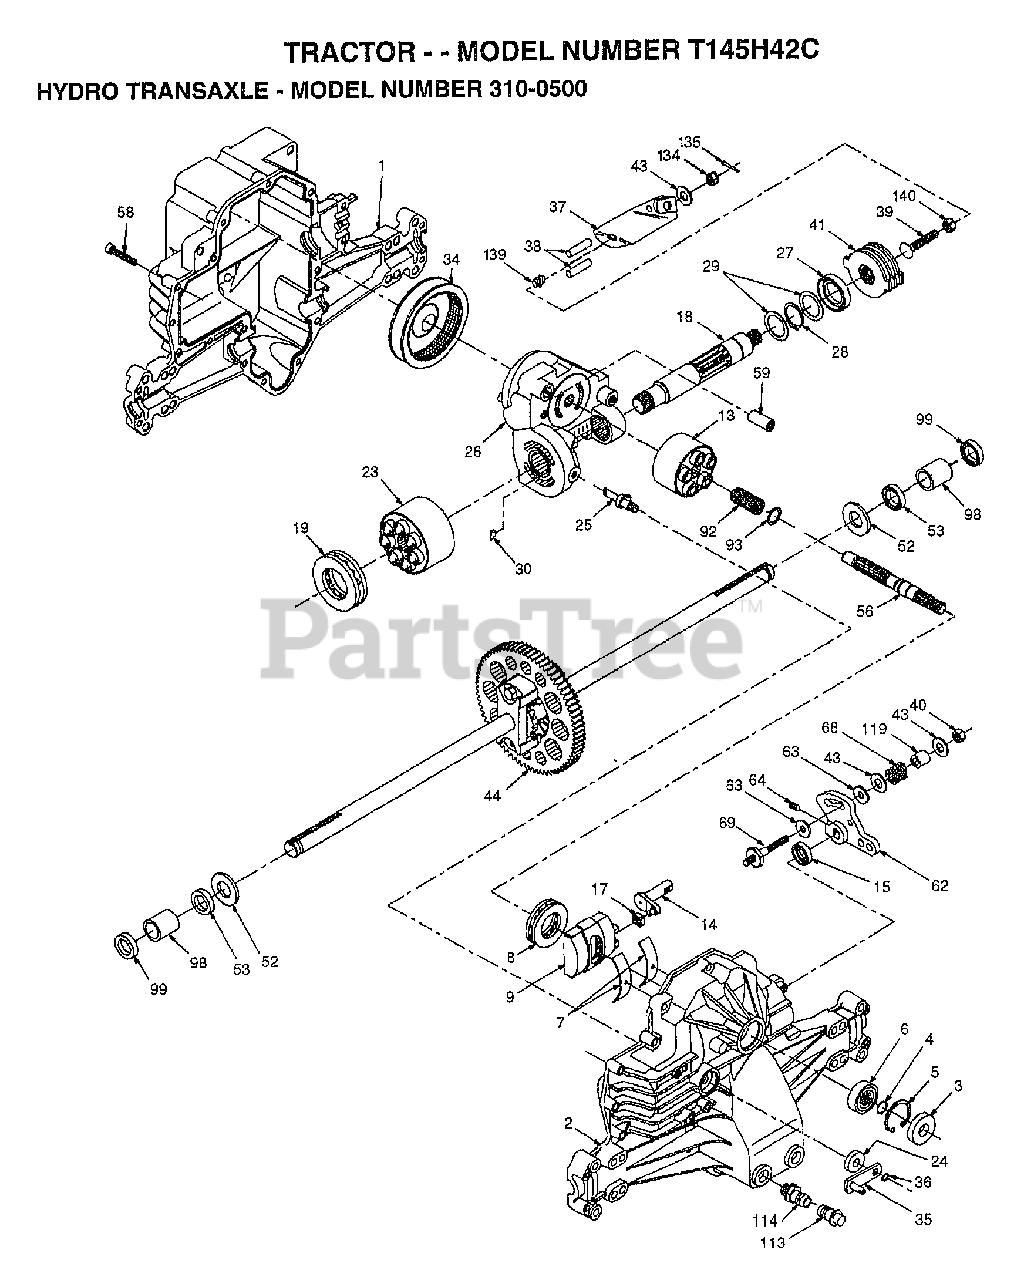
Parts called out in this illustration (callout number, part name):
1	HOUSING.L.44863RM
2	HOUSING.UPR.70122
3	SEAL.9008000-0128
4	RING.RET.2003016.
5	RING.RET.2003052.
6	BEARING.(50552)42X68X16
7	CRADLE- 2003023.
8	BEARING.THU.50551
9	SWASHPLT.2003087.
13	BLOCK.CLYN.70079.
14	ARM.TRUN.2003005.
15	SEAL.9008000-0126
17	GUIDE.2000015.
18	SHAFT.MOTOR.50449
19	BEARING.THU.50552
23	BLOCK.CYLIN.70082
24	SEAL.LIP.45074
25	ACTUATOR.2003555
26	KIT.CEN.SEC.70250
27	SEAL.LIP.45075
28	RING RETAIN 50007
29	WASHER.44872
34	ELEMENT.OIL.44964
35	ARM.BYPASS.50270
36	RING.RETAIN.44870
37	ARM.ACTUAT.23710
38	PIN.ACTUAT.44891
39	BOLT.50316
40	NUT.LOCK.HX.50317
41	KIT.BRAKE.70135
43	WASHER HYD 44130
44	DIFFERNTIAL.70126
52	WASHER.HYD.44875
53	SEAL.HYDRO.45076
56	SHAFT.INPUT.50005
58	BOLT.1/4-20.44876
59	PIN.HYDRO.50002
62	ARM.CONTROL.50254
63	PUCK.DAMPER.50281
64	SCREW.SET.50018.
68	SPRING.HYD.50277
69	STUD.5/16-24.DANA
92	SPRING.2003014.
93	WASHER.2003017
98	BEARING.SLV.50137
99	SEAL.WIPER.50941
113	CAP.VENT.70109
114	O-RING.ASM.70110
119	SPACER.HYD.50278
134	NUT.CAS.HYD.44142
135	PIN.COT.HYD.44101
139	SPRING.COMP.50431
140	NUT.HEX.50269
